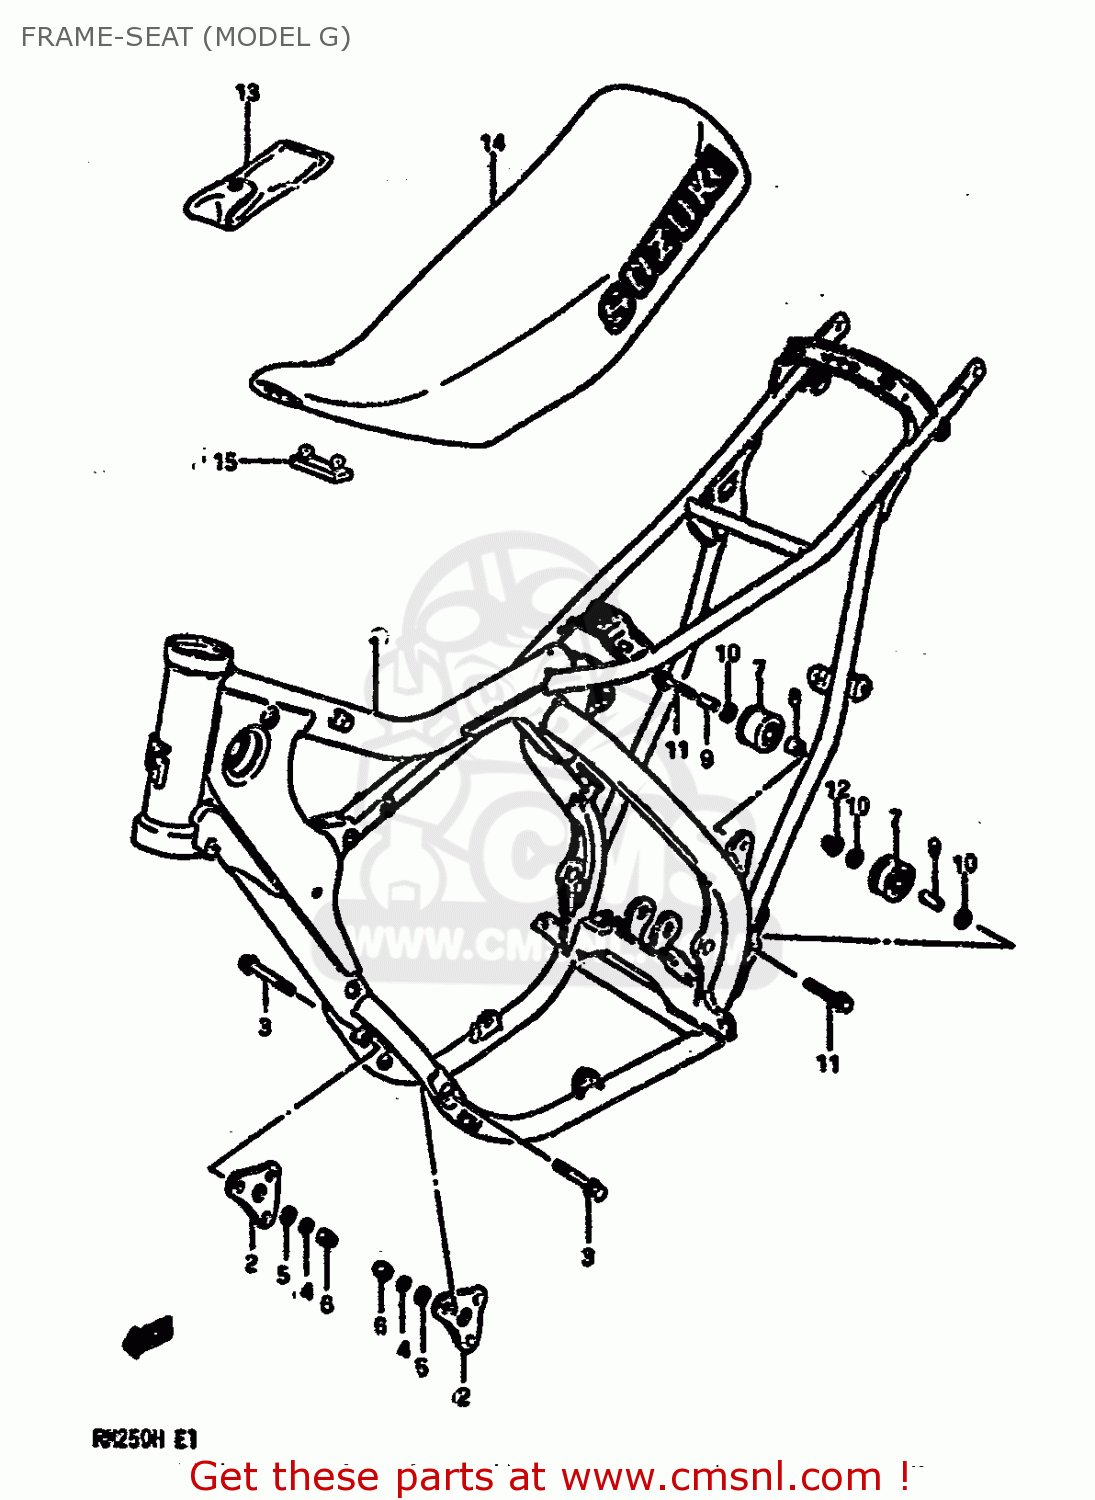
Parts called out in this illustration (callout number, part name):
1	FRAME
2	PLATE,ENGINE MOUNTING
3	BOLT 8X55
4	LOCK WASHER
5	WASHER
6	NUT
7	ROLLER,CHAIN CONTROL UPPER
8	SPACER (8.5X15X10)
9	SPACER(8.6X12X25.5)
10	WASHER
11	BOLT(8X45)
12	NUT
13	TOOL SET
14	SEAT ASSEMBLY
15	CUSHION
